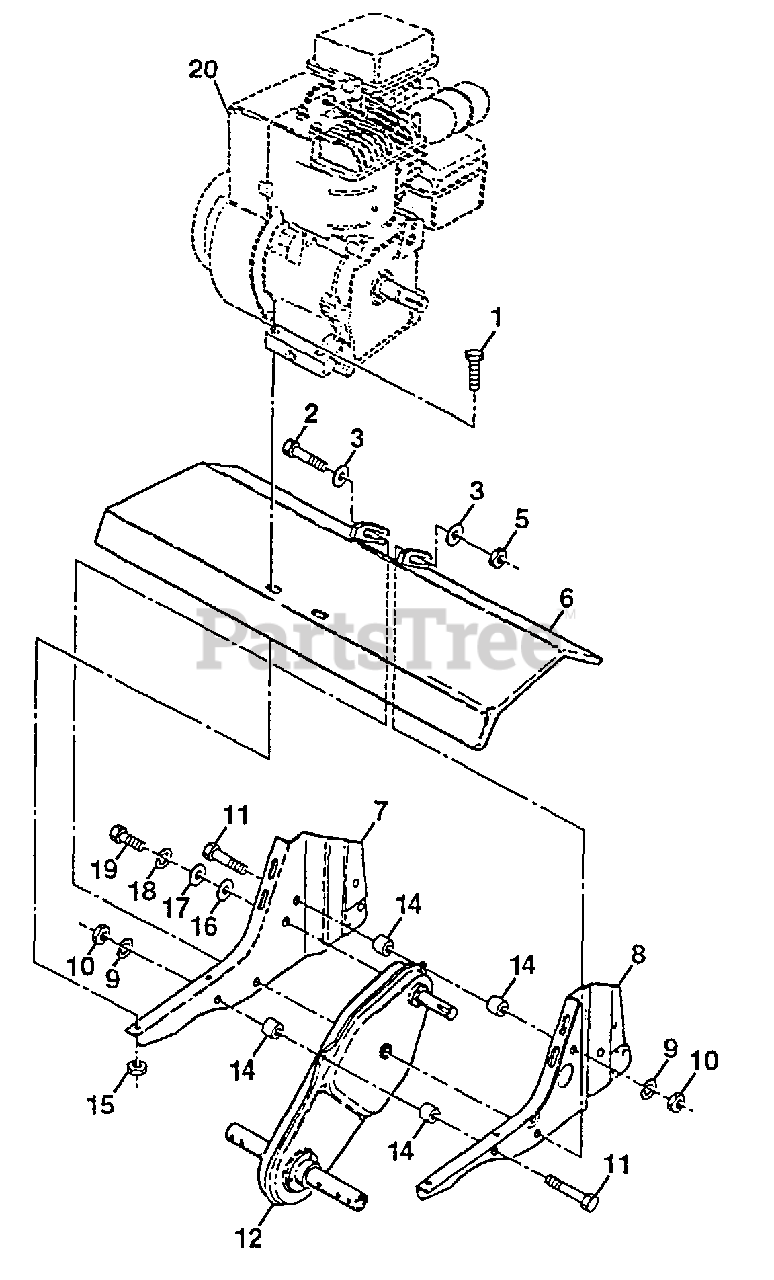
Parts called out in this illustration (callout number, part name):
1	Bolt, Hex 5/16-18 x 1-1/2
2	Bolt, Hex 3/8-16 x 3-1/4
3	Washer 13/32 x 13/16 x 11 Ga.
5	Locknut, w/Insert 3/8-16
6	Shield Tine
7	Bracket, Engine, R.H.
8	Bracket, Engine, L.H.
9	Washer, Lock 5/16
10	Nut, Hex 5/16-18
11	Bolt, Hex 5/16-18 x 2-3/4 (AYP part number)
12	Transmission
14	Spacer, Split
15	Nut, Keps 5/16-18
16	Washer 9/32 x 7/8 x 12 Ga.
17	Washer 9/32 x 1-1/4 x 16 Ga.
18	Washer, Lock 1/4
19	Bolt, Hex 1/4-28 x 3/4 Gr. 5
20	Engine Briggs
